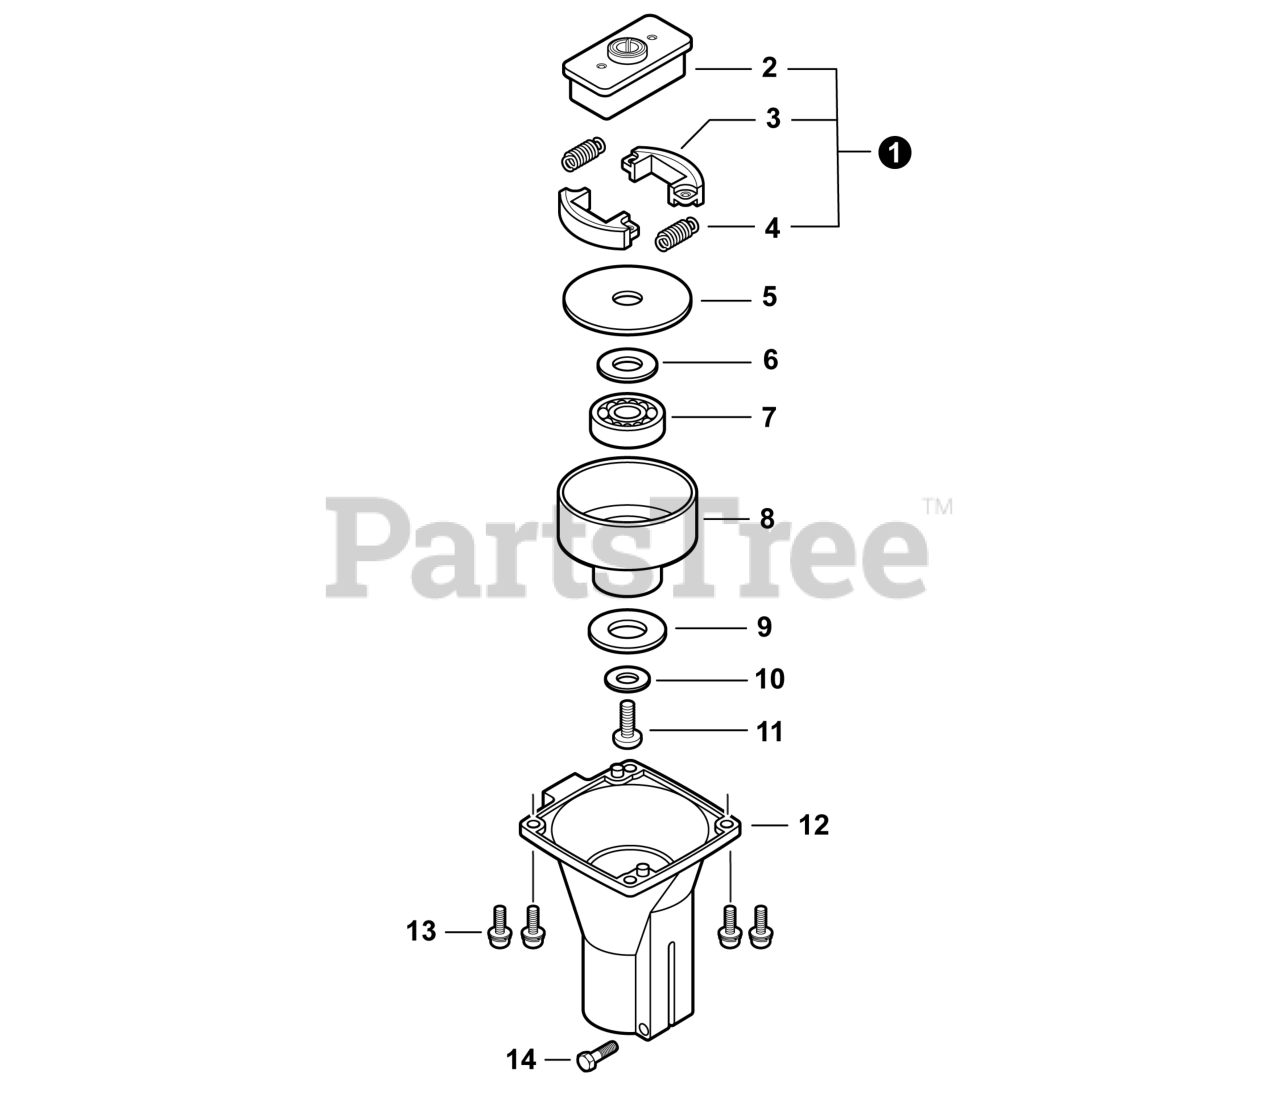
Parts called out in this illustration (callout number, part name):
1	CLUTCH ASSY
2	HUB, CLUTCH
3	SHOE, CLUTCH
4	SPRING, CLUTCH
5	PLATE, CLUTCH
6	WASHER 10.5x18x1.6
7	BEARING, BALL 6000-2RLB
8	DRUM, CLUTCH
10	WASHER, CLUTCH
11	SCREW 6x12
12	CASE, CLUTCH
13	SCREW 4x18
14	BOLT 5
